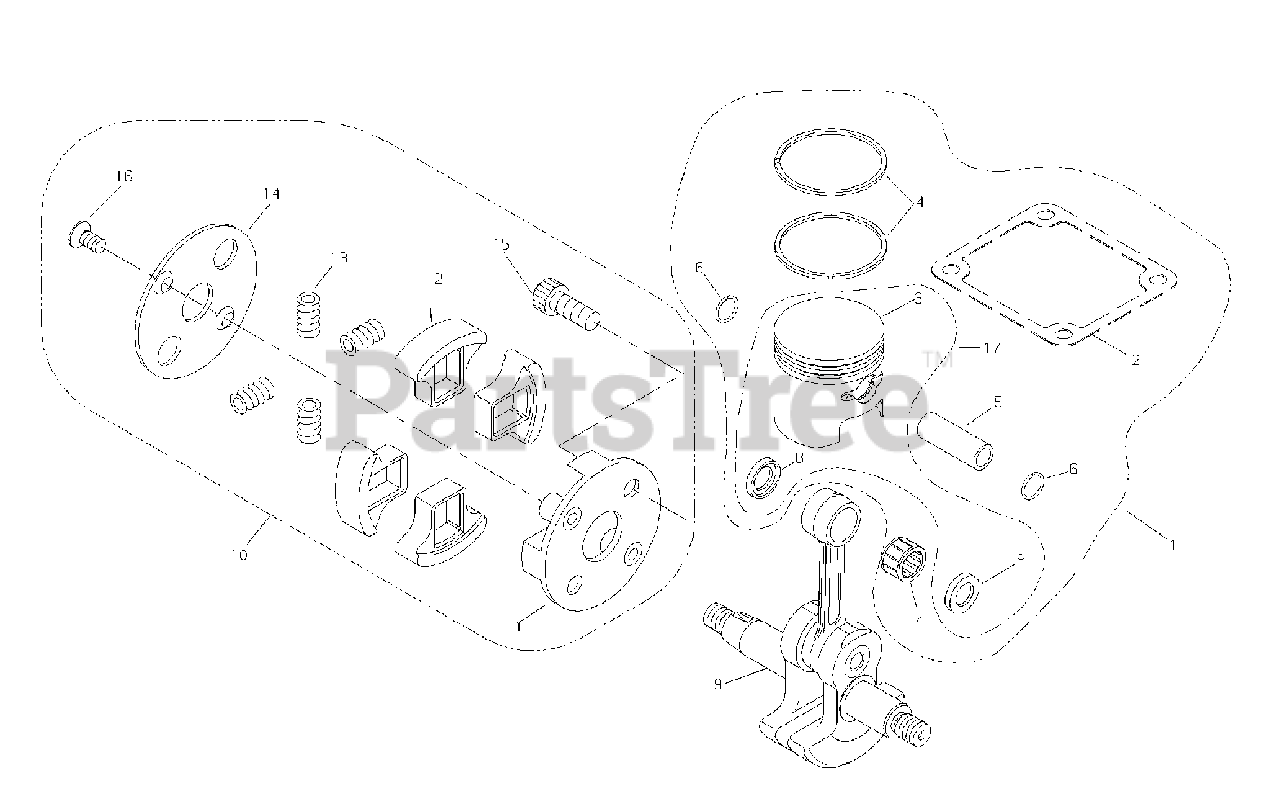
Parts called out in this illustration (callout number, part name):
1	PISTON KIT
2	GASKET, CYLINDER
3	PISTON
4	RING, PISTON
5	PIN, PISTON
6	RING, RETAINING
7	BEARING, NEEDLE
8	SPACER, PISTON
9	CRANKSHAFT ASSY
10	CLUTCH ASSY
11	HUB, CLUTCH
12	SHOE, CLUTCH
13	SPRING, CLUTCH
14	PLATE, CLUTCH
15	BOLT, CLUTCH
16	SCREW
17	PISTON SET
